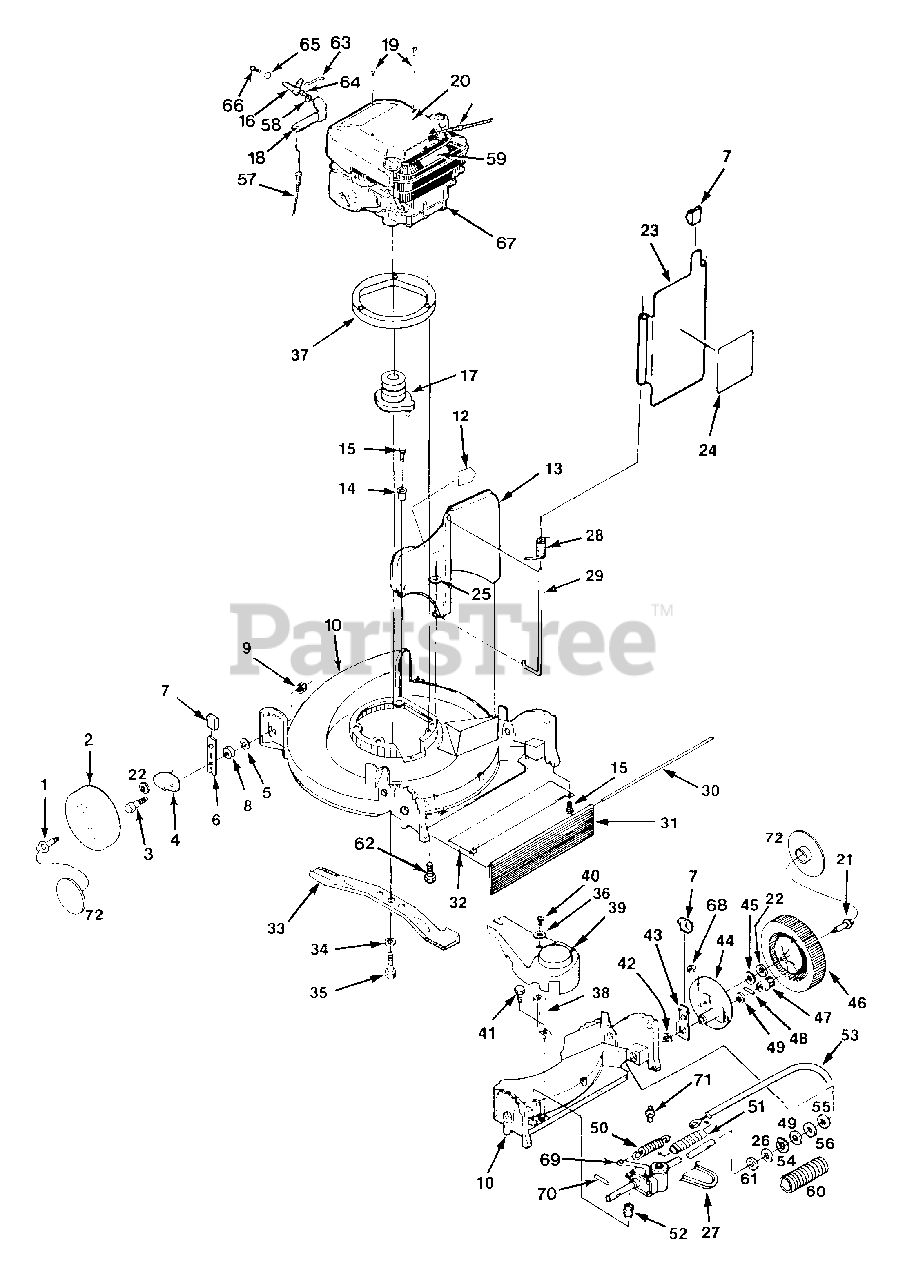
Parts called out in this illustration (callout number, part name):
1	BOLT - Shldr 3/8-16 x 2
2	WHEEL - Front
3	BOLT - Shldr 5/16-18 x 1 3/4
4	ARM - Height adj
5	WASHER - Flat 5/16
6	SPRING - Index
7	KNOB - Index spring
8	SPACER - Index spring
9	NUT - Flange (5/16-18)
10	DECK - 21"
12	DECAL - chute
13	CHUTE - Discharge
15	SCREW - (1/4-20 x 3/4")
16	BELLCRANK
17	ADAPTER - Blade
18	THROTTLE BRACKET
19	SCREW - #8-32 x 1-1/4 Phil Tap
20	COVER - Engine
21	BOLT - shldr 3/8-16 x 2
22	WASHER - Bellville
23	DOOR - Chute
24	DECAL - Door
25	WASHER - Flat (1/4")
27	BELT - Drive
28	SPRING - Door
29	PIN - Hinge
30	ROD - Drag flap
31	FLAP - Drag
32	COVER - Rear
33	BAR - Cutter 21"
34	WASHER - Lock (3/8")
35	BOLT (3/8-24 x 1 1/4")
36	WASHER - Plain
37	RING - Engine
38	SUPPORT - cover
39	COVER - Drive
40	SCREW - Rd hd phil (1/4-20 x 3/4")
41	SCREW - Hex hd (10-16 x 1/2")
42	SPACER - Hgt. Adj
43	SPRING - Index
44	DRIVE WHEEL SUPPORT
45	WASHER - Flat
46	WHEEL - rear w/gear
47	PINION (R.H.)
49	WASHER - Flat
50	SPRING - Traction cable
51	COVER - Spring
52	SPRING - Compression
53	CABLE - Traction
55	WASHER - Spring
57	CONTROL - Throttle w/cable
58	SPACER - stepped
59	DECAL - Danger
60	COVER - Drive Shaft
61	WASHER - Thrust
62	SCREW - Hex 3/8-16 x 2 1/4
63	THROTTLE LINK
64	SCREW - #10-24 x 3/8" Hex Tap
65	WASHER - 3/4" FLAT
66	SCREW - #10-24 x 3/4" Hex Tap
67	Engine
68	NUT - 3/8-16 Flg Lock
69	TRANSMISSION
70	ROLL PIN - 1/8 x 7/8
